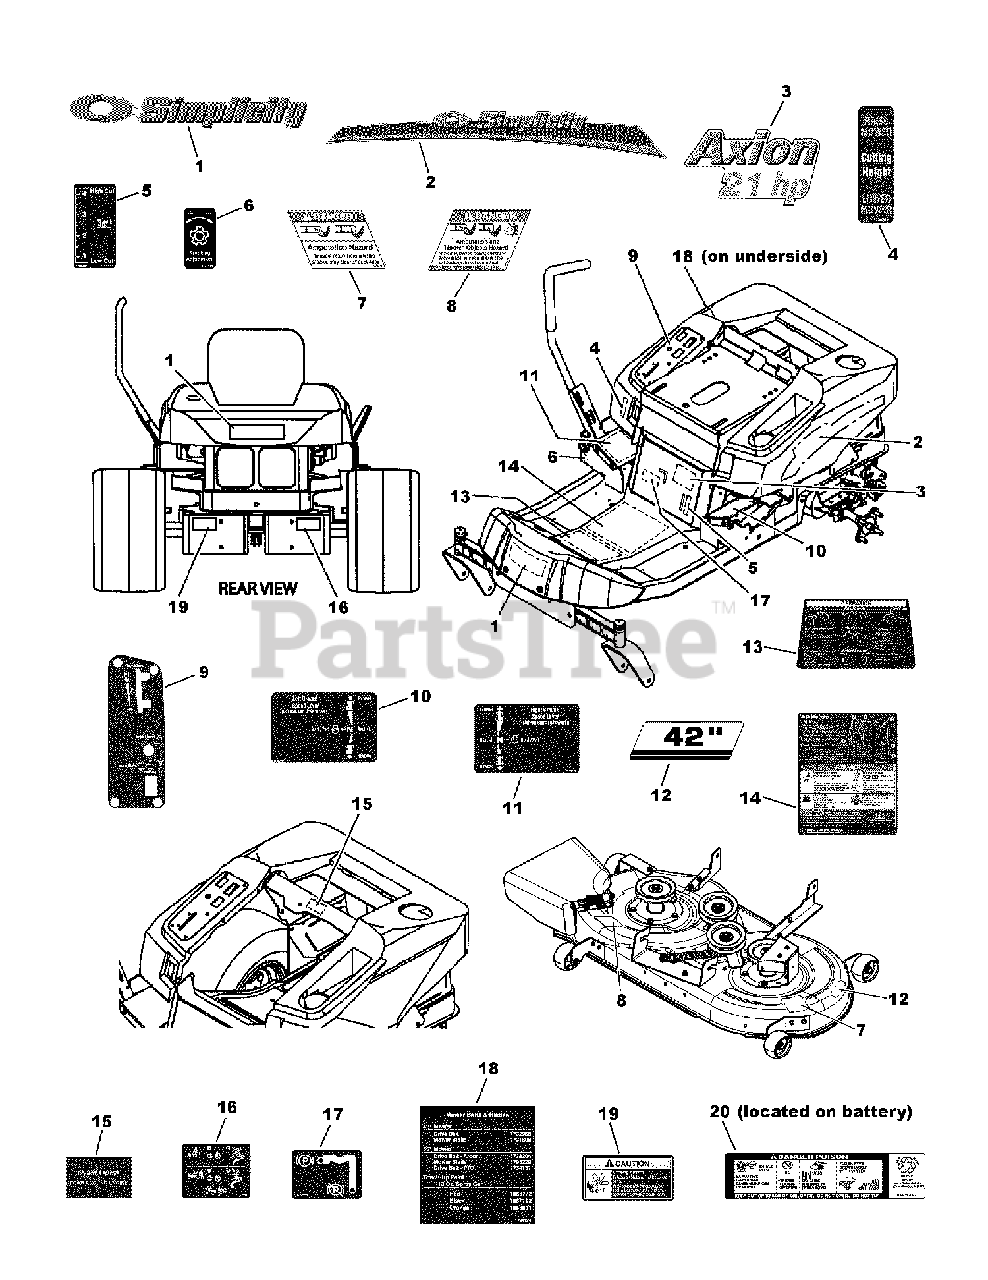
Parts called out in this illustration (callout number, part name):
1	DECAL, Simplicity Logo
2	DECAL, Stripe LH, Axion
3	DECAL, Model Axion 21HP
4	DECAL, Mower Cutting Height ZTS 7500
5	DECAL, Height-Of-Cut
6	DECAL, Tracking Adjustment ZT 7000
7	DECAL, Danger- Do Not Put Hand/Feet in Mower
8	DECAL, Danger- Do Not Operate w/o Deflector
9	DECAL, Instrument Panel ZTS 7600
10	DECAL, LH Handle Control ZTS 7500
11	DECAL, RH Handle
12	DECAL, 42" Deck
13	DECAL, Handles Operation
14	DECAL, Operator Instructions
15	DECAL, Do Not Remove Foam Around Engine
16	DECAL, Transmission Release ZTS Export
17	DECAL, Parking Brake, ZT
18	DECAL, Belt/Blade, ZT
19	DECAL, Caution, Cut Hazard
20	DECAL, Danger Poison
